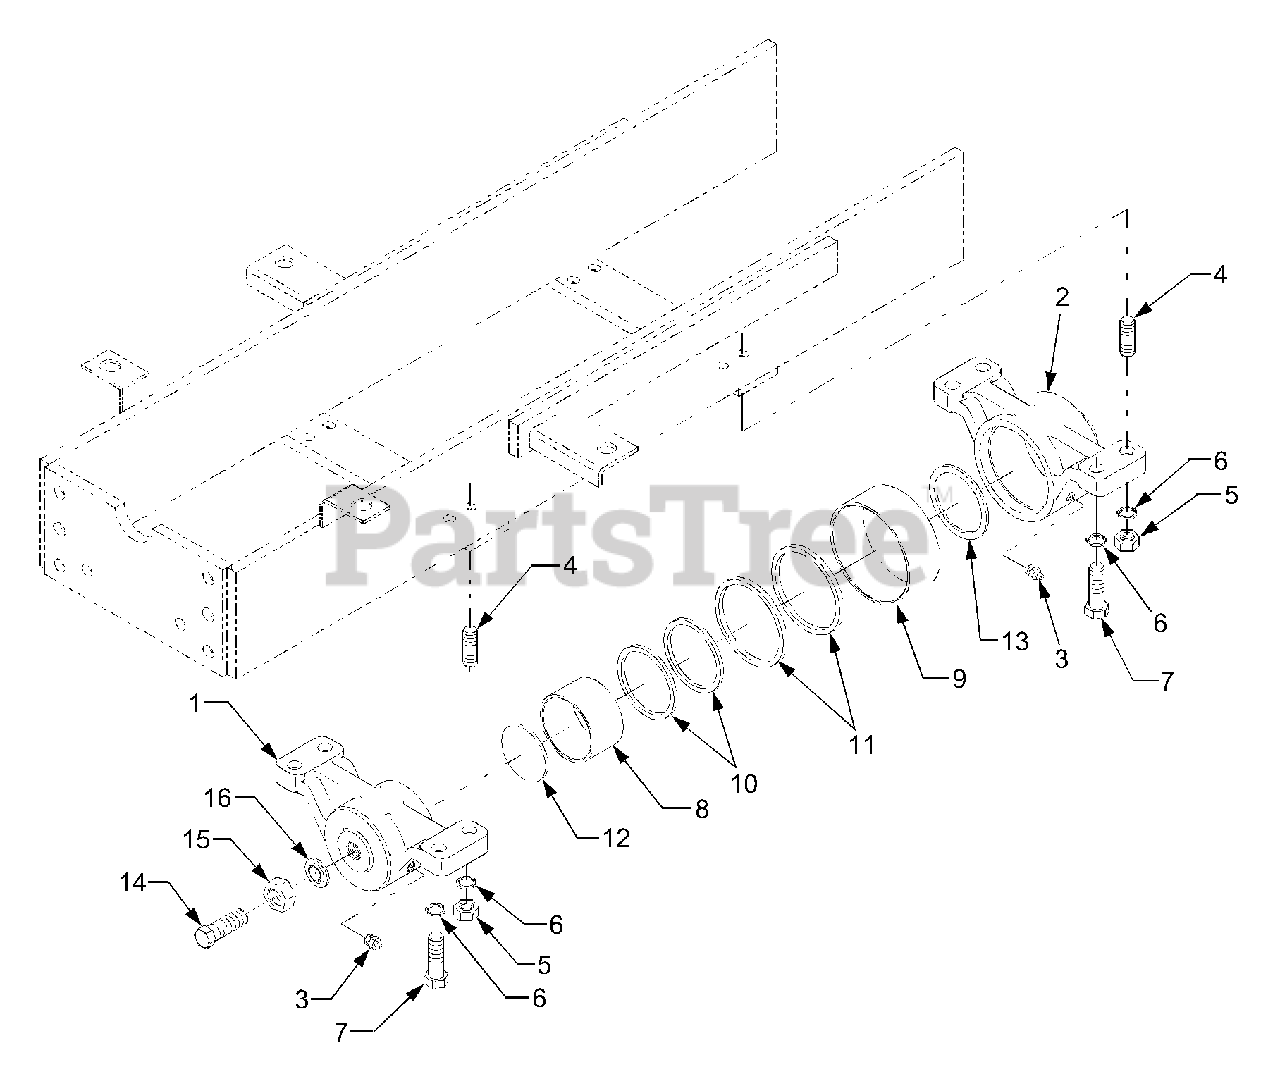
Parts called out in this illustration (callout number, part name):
1	Bracket, Front
2	Bracket, Rear
3	Nipple, Grease
6	Washer, Spring
12	Plate, Adjust
13	Collar, Thrust
